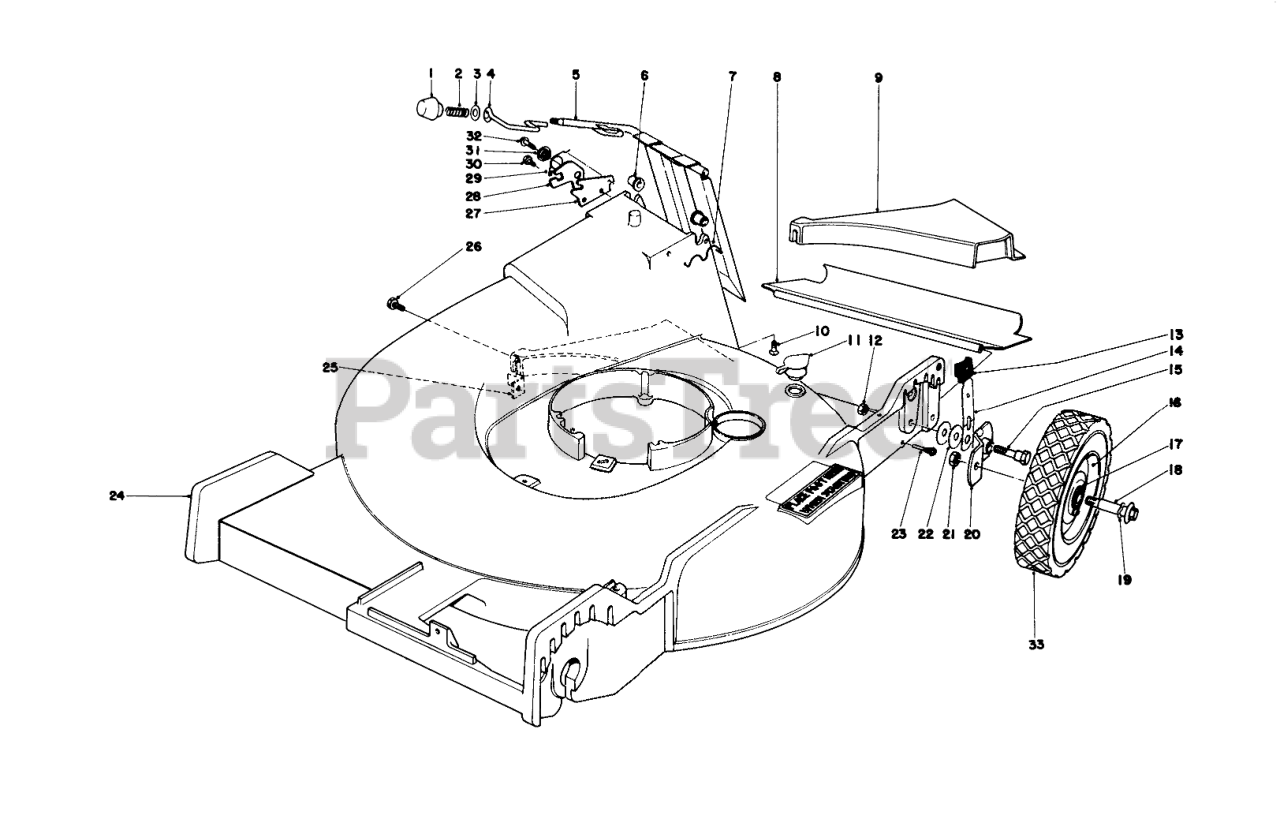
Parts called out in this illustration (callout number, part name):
2	COMPRESSION SPRING
3	WASHER
4	DOOR LATCH
5	Door Handle
6	BUSHING-NYLON
7	Door Retainer
8	REAR SAFETY SHIELD
9	REAR INSERT
10	SCREW-HH
11	WASHOUT PLUG
12	Nut
13	KNOB-ARM
14	SPRING ARM ASM
15	PIVOT SCREW
16	Wheel & Tire Assembly (Incl. Ref. #17 & 33)
17	BEARING-BALL
19	SPRING WASHER
20	PIVOT ARM ASM A
21	Nut
22	WASHER-PIVOT
23	SAFTEY SHIELD SCREW
24	Housing
25	SPECIAL NUT
26	SCREW THD 1/4 20 5/8
27	DOOR LATCH PLATE
28	Latch Safety
29	TORSION SPRING
30	SCREW-HWH
31	Latch Spacer
32	Screw
